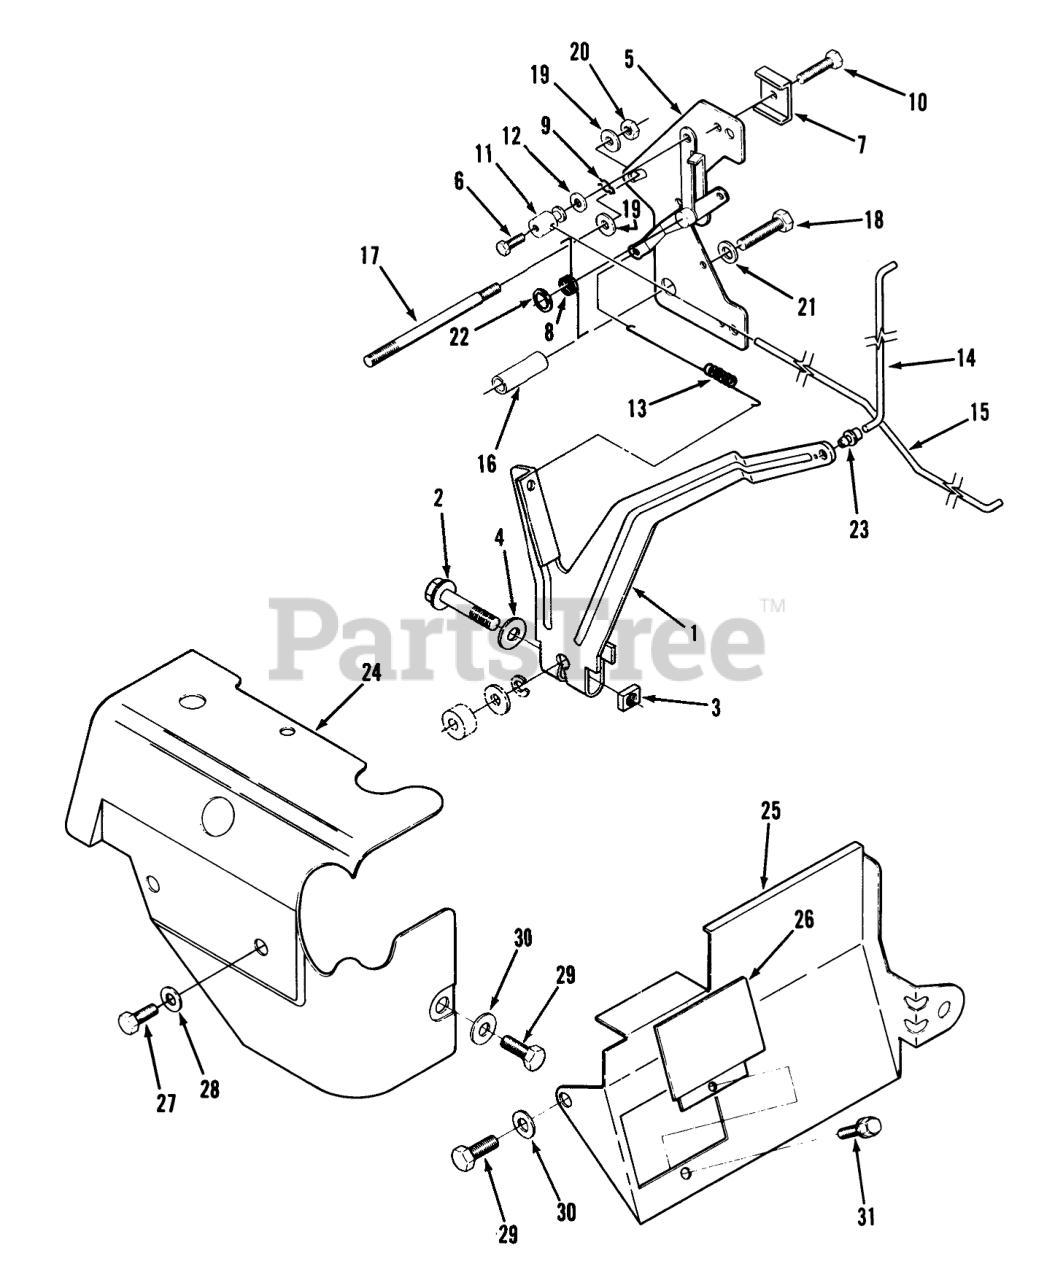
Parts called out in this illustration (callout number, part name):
1	LEVER-GOVERNOR
2	HHCS-M8 X 35MM
3	Nut
4	Washer
5	PLATE-ASS'Y THROTTLE
6	HHMS #8-32X3/8"
7	Plug-Pipe
8	SPRING-CHOKE LINKAGE
9	Cotler Pin
10	HWHTF-SCRW M5X12MM
11	SWIVEL-CHOKE LEVER
12	Washer
13	SPRING-GOVERNOR
14	LINK-THROTTLE
15	LINK-CHOKE
16	SPACER
18	HHCS-M8 X 40MM
19	Washer
20	NUT-HEX M6
21	Nut-M8
22	RING-RETAINER
23	Clip-Link
24	HSG-CYL AIR
25	Air Deflector
26	Cover
27	HHCS-M6 X 10MM
28	Washer
29	HHCS-M8 X 10MM
30	Nut-M8
31	Bolt
